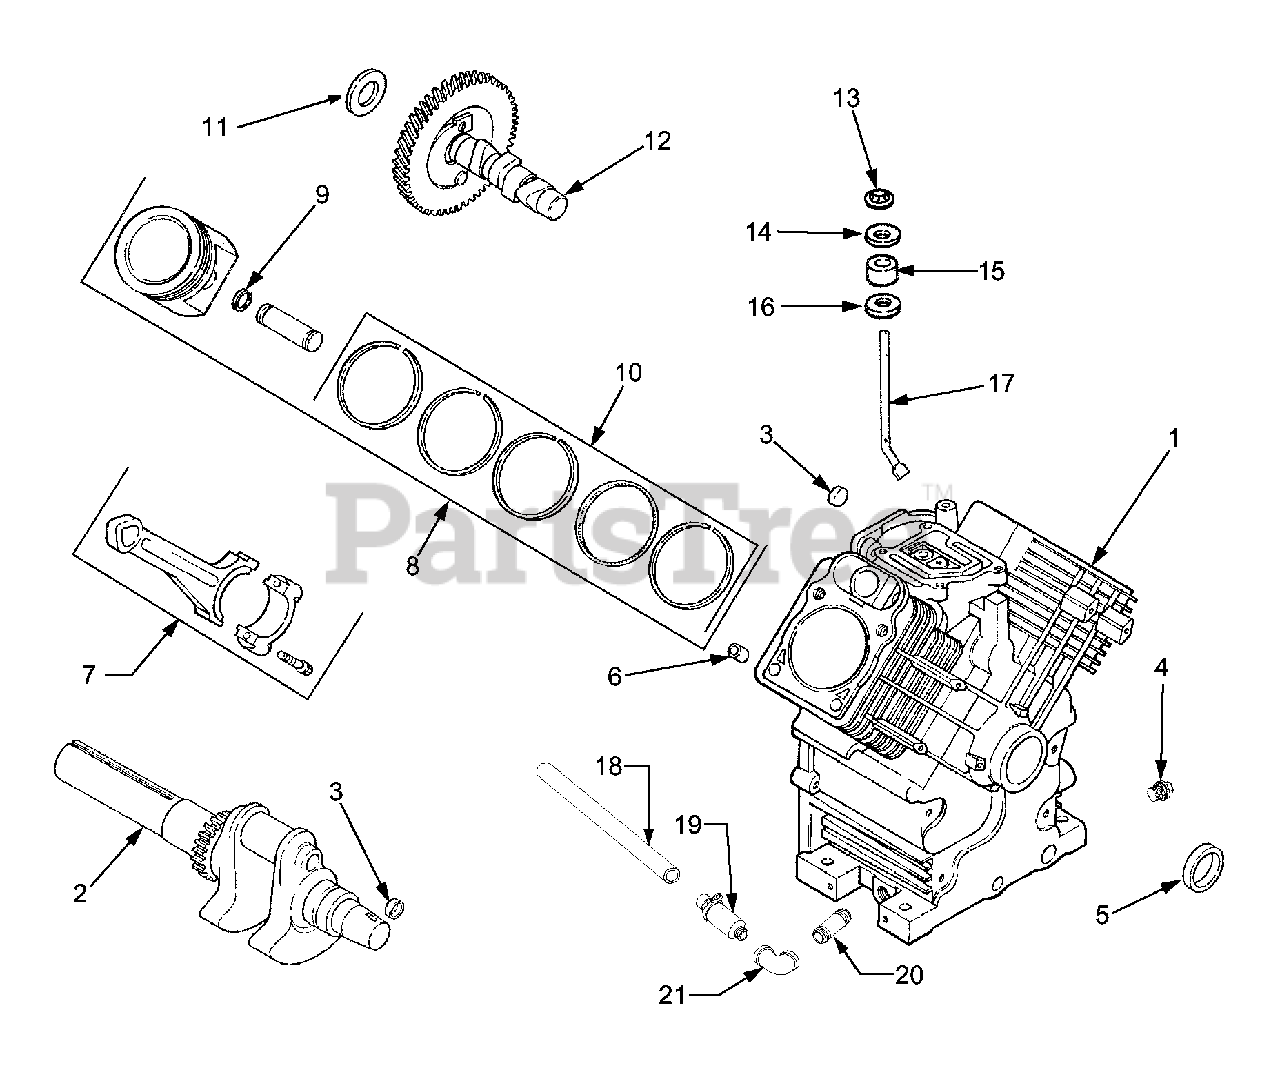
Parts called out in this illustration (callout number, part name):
1	Engine, Complete
2	Crankshaft
3	Plug, Cup
4	Plug, Hex Head, 3/8 NPTF
5	Seal, Oil
6	Pin, Locating
7	Rod, Connecting, Std
8	Piston w/Ring Set, Std
9	Retainer, Piston Pin
10	Ring Set, Std
11	Shim, Camshaft, .0320
12	Camshaft
13	Ring, Retainer
14	Washer, Nylon
15	Seal, Governor Cross Shaft
16	Washer, Plain
17	Shaft, Governor Cross
18	Hose, Oil Drain
19	Drain, Oil
20	Pipe, Straight
21	Elbow, 90 °
